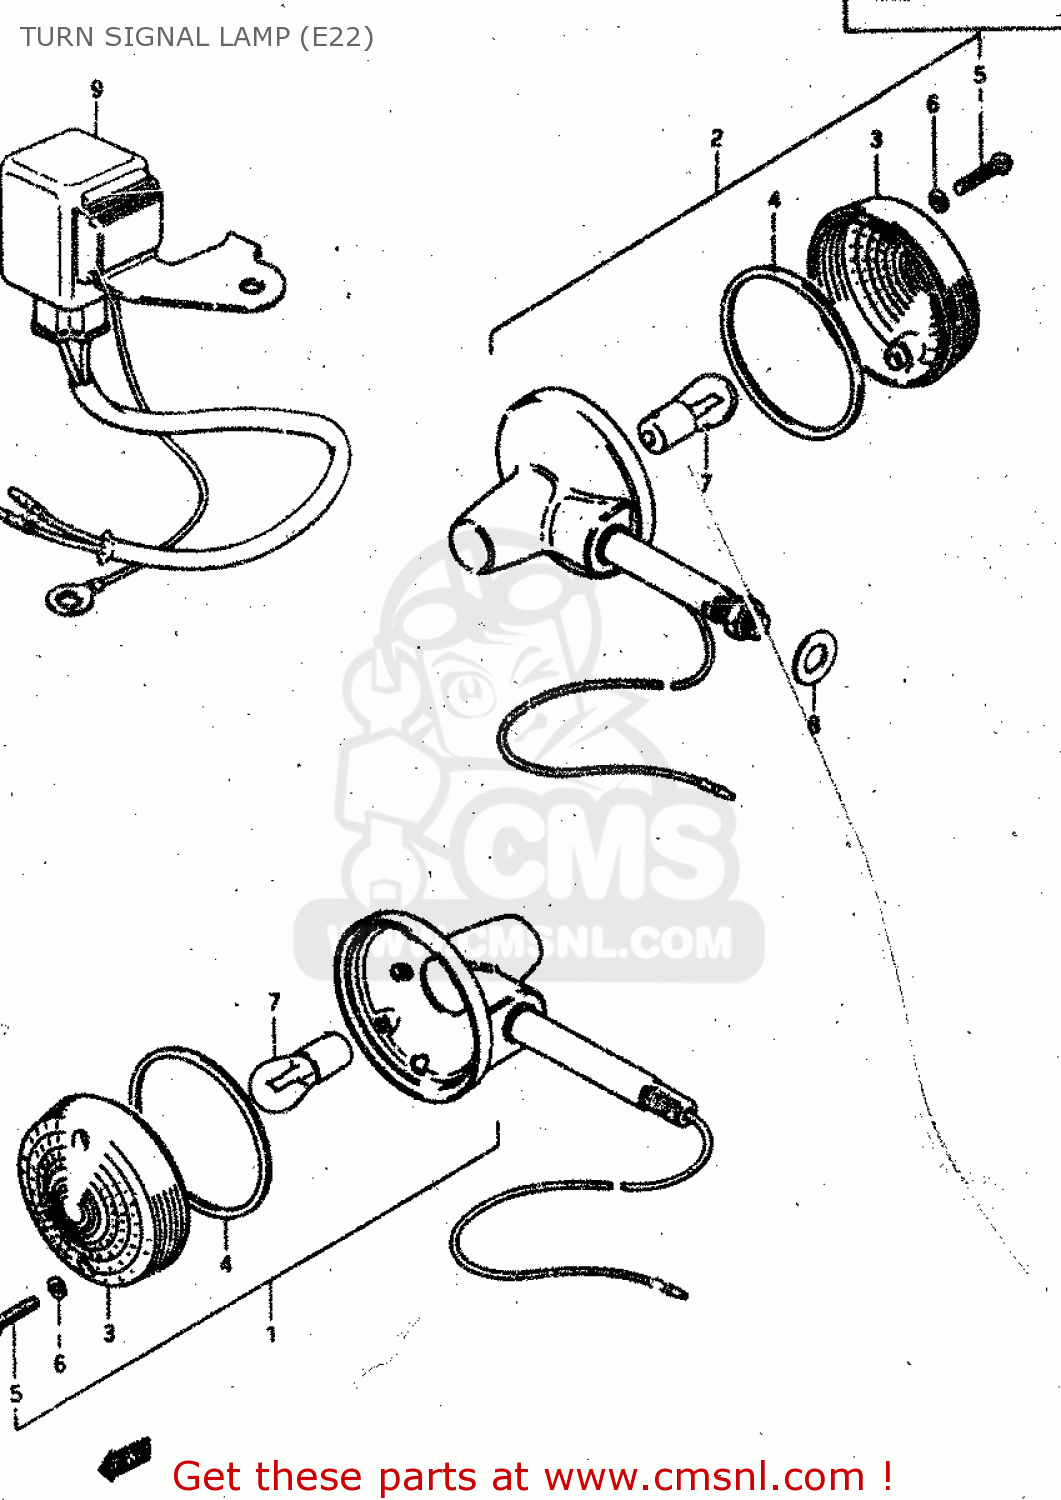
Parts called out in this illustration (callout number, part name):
1	LAMP, FRONT TURN SIGNAL
2	LAMP, REAR TURN SIGNAL
3	LENS
4	GASKET (NAS)
5	SCREW 4X25
6	GASKET (NAS)
7	BULB (6V,21W)
8	WASHER
9	RELAY, TURN SIGNAL
